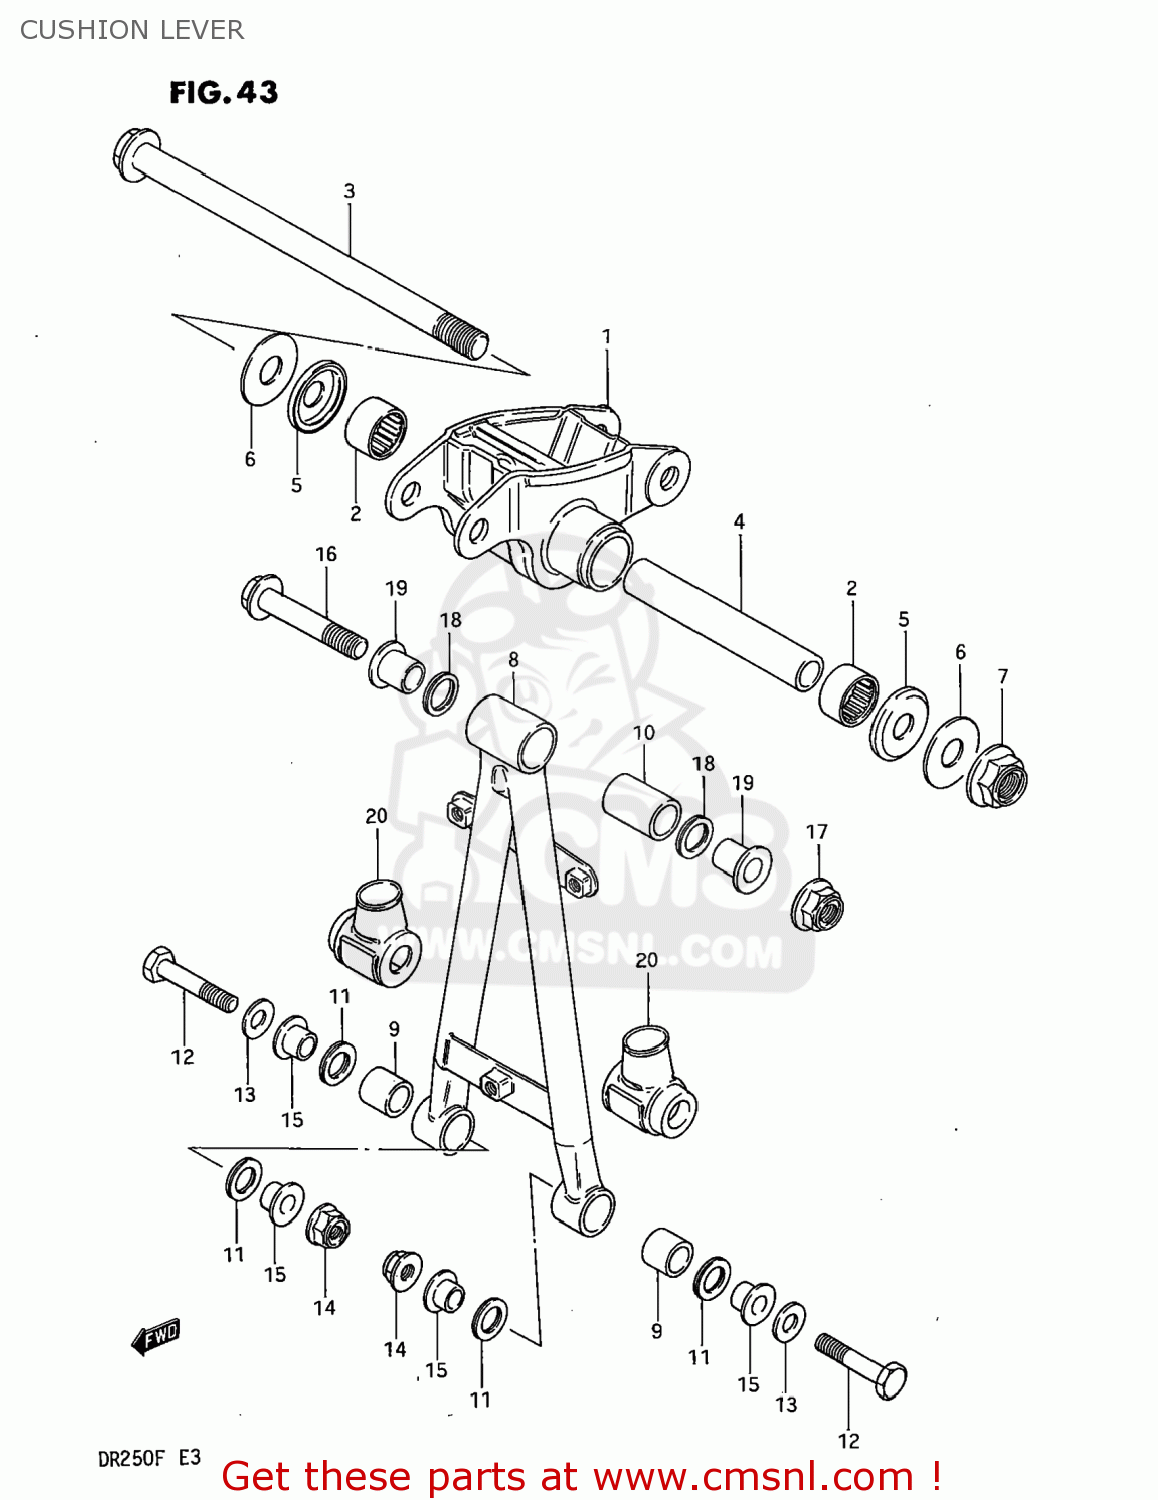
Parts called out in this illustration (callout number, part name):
1	LEVER SET,REAR CUSHION
2	BEARING(17X25X20)
3	SHAFT,REAR CUSHION LEVER
4	SPACER
5	DUST SEAL,RR CUSHION LEVER
6	WASHER
7	NUT 12MM
8	ROD SET,REAR CUSHION LEVER
9	BUSHING
10	BUSH,UPPER
11	DUST SEAL,RR CUSHION LOD LWR
12	BOLT,REAR CUSHION LEVER
13	WASHER
14	NUT
15	SPACER,RR CUSHION ROD LWR
16	BOLT(10X65)
17	NUT
18	DUST SEAL,LEVER CUSHION UNIT
19	SPACER,RR CUSHION ROD UPR
20	BOOT,REAR CUSHION ROD,LOWER
